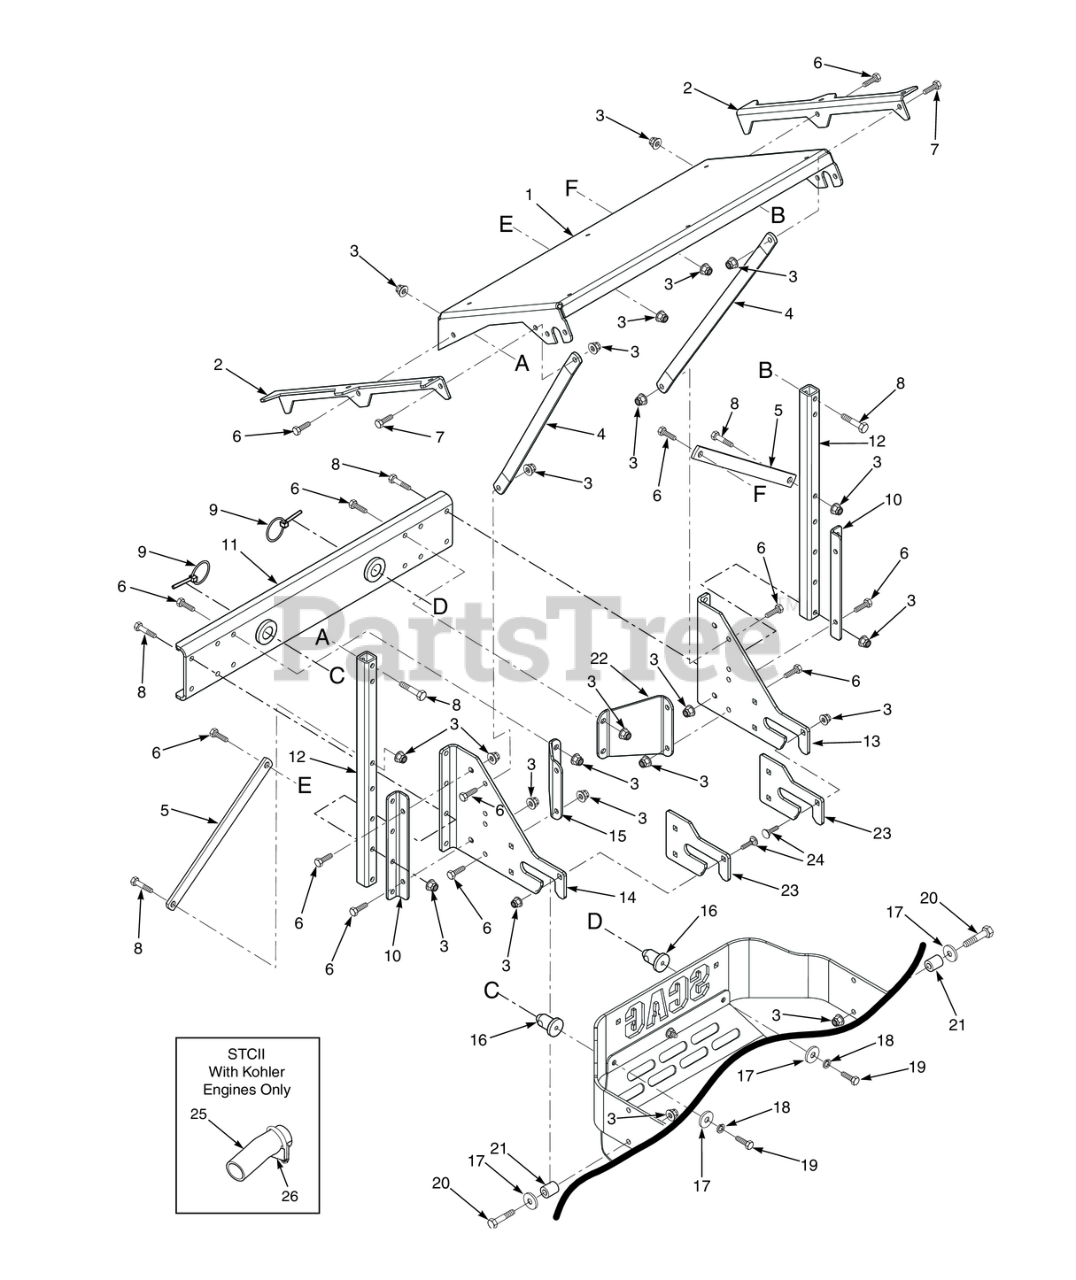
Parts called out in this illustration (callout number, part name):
1	Support Frame, Hopper
2	Bracket, Hopper Support
3	Nut, Flange Elastic Stop Nut, 3/8-16
4	Brace, Stiffener
5	Brace, Engine Mounting
6	Bolt, Hex Head, 3/8-16 x 1 Gr. 5
7	Bolt, Hex Head 3/8-16 x 1-1/4" Grade 8
8	Bolt, Hex Head 3/8-16 x 2-1/4" - 61"
9	Quick Pin, 5/16" Dia.
10	Mounting Bracket, Tube
11	Mounting Bracket Weldment
12	Tube, Upright
13	Mounting Bracket, GC R.H.
14	Mounting Bracket, GC L.H.
15	Angle Bracket, GC
16	Pin, GC Locator
17	Flatwasher, 3/8-.406 x 1-1-1/2 x 7 Gauge
18	Lockwasher, 3/8" Spring, Kawasaki FX / FS
19	Bolt, Hex Head 3/8-16 x 1-1/4" Grade 8
20	Bolt, Hex Head 3/8-16 x 2-1/4" - 61"
21	Spacer
22	Angle Bracket, GC
23	Wear Plate, GC
24	Carriage Bolt, 3/8-16 x 1-1/4"
25	TUBE, EXHAUST
26	Clamp, Muffler (Clamp Only)
